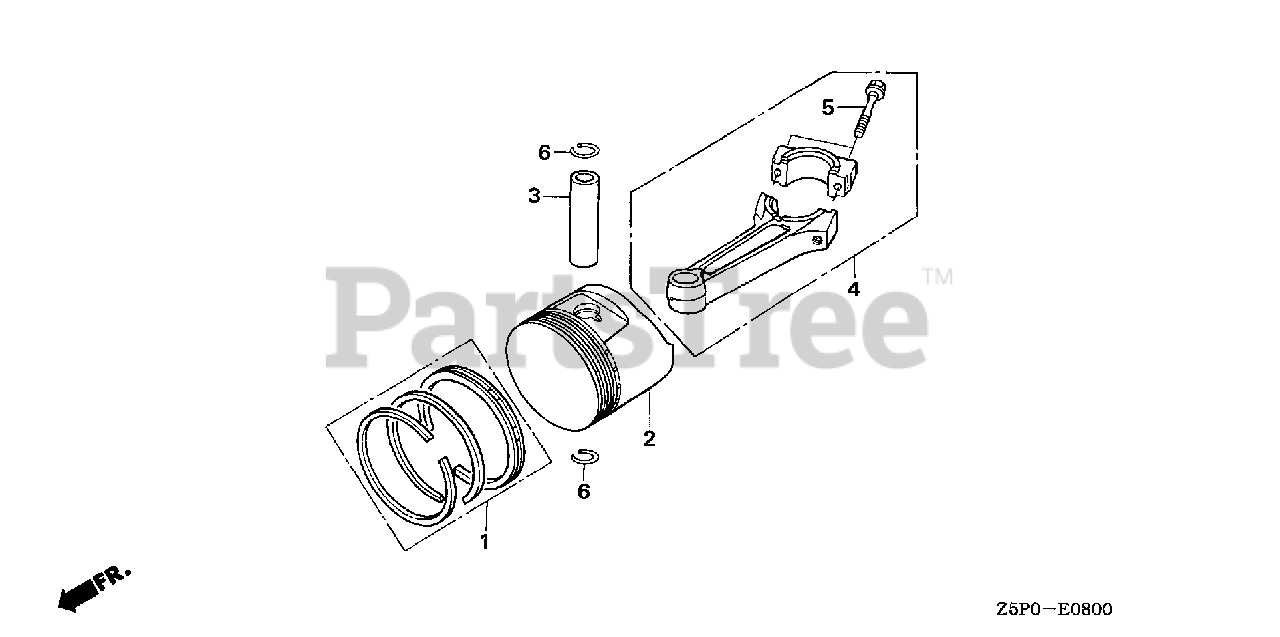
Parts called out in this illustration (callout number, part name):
1	RING SET, PISTON (STD) (RIKEN)
1	RING SET, PISTON (0.25)
1	RING SET, PISTON (0.50)
1	RING SET, PISTON (0.75)
2	PISTON (STD)
2	PISTON (0.25)
2	PISTON (0.50)
2	PISTON (0.75)
3	PIN, PISTON
4	ROD ASSY., CONNECTING (STD)
4	ROD ASSY., CONNECTING
5	BOLT, CONNECTING ROD
6	CLIP, PISTON PIN (20MM)
